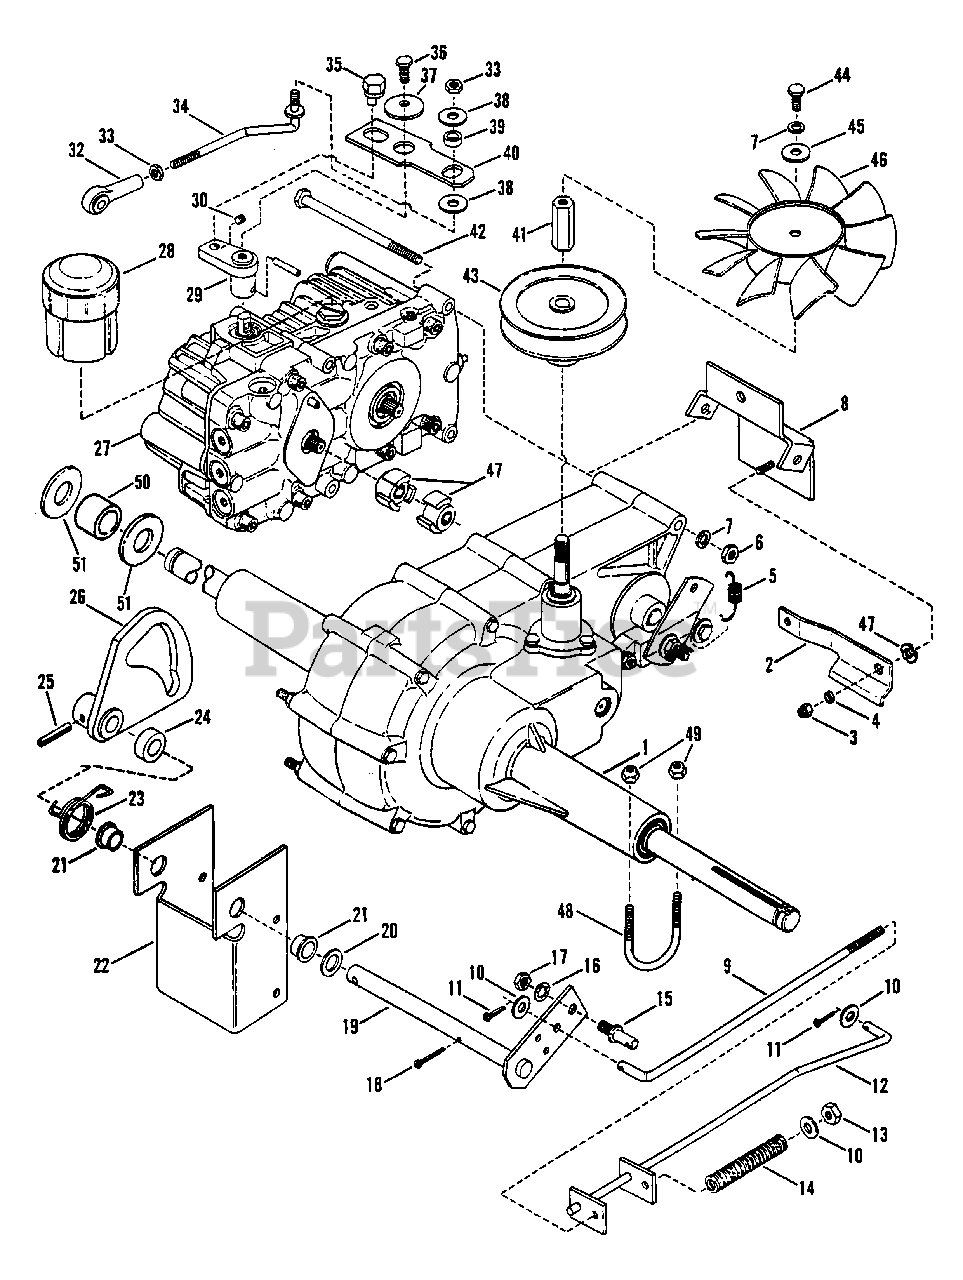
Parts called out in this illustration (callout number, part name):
1	TRANSAXLE ASSEMBLY (HG, 215-1000)
2	LEVER, Release
3	NUT, 1/4-20 Hex Lock
4	SPACER .37 OD x .271 ID x .120 L
5	SPRING, Brake Return
6	NUT, 5/16-18 Hex
7	WASHER, 5/16 Split Lock
8	TORQUE BRACKET ASSEMBLY
9	ROD, Brake Spring
10	WASHER 5/16 x 7/8 x .083
11	COTTER-PIN, 5/32 x 1"
12	ROD, Brake Stop
13	NUT, 5/16-18 Hex Center Lock
14	SPRING, Brake
15	STUD, Neutral Pivot
16	WASHER, 3/8 Internal Tooth Lock
17	NUT, 3/8-24 Hex
18	COTTER-PIN, 1/8 x 1-1/4"
19	NEUTRAL PIVOT ASSEMBLY
20	WASHER
21	BEARING, 5/8 Flanged Nylon .625 ID x .719 x .325 (No longer available)
22	SUPPORT, Neutral Pivot
23	SPRING, Torsion
24	SPACER, 1.120 OD x .635 ID x .38 L (No longer available)
25	PIN, Roll, 1/4 x 1-1/4"
26	CAM, Neutral Return
27	TRANSMISSION, Hydro (HG BDU-105-120)
28	RESERVOIR ASSEMBLY (HG 2003081)
29	HUB, Speed Control
30	SCREW, 1/4-28, 1/8 Hex Socket Set (No longer available, try using 7077667)
31	PIN, Spiral 5 MM x 36 MM
32	BALL JOINT, 5/16-24
33	NUT, 5/16-24 HeX
34	ROD, Adjustment 4.41" l, 5/16-24 Ends (No longer available)
35	PIN, Eccentric
36	SCREW, 5/16-18 x 1/2" Hex Head Cap
37	WASHER, Cone .32 x 1.4 x .1
38	WASHER, Flat .327 x .875 x .09
39	ROLLER
40	PLATE, Speed Control
41	NUT, Special 3/4 Hex Stock/5/16-24 Thru/9/16-18x1.0 Deep (No longer available)
42	SCREW, 5/16-18 x 4-1/2, Hex Head Cap
43	PULLEY, Drive
44	SCREW, 5/16-24 x 1/2" Hex Head Cap
45	WASHER, Fender 5/16
46	FAN, 7" DIA 10 Blade
47	Coupler
48	U-BOLT 5/16-18
49	NUT, 5/16-18 Hex Flange Lock (Torque to 23 ft/lbs.)
50	SPACER, 3/4" I.D. x 2-1/4" Long
51	WASHER, 3/4" Flat
52	WASHER, 3/8 Wave
